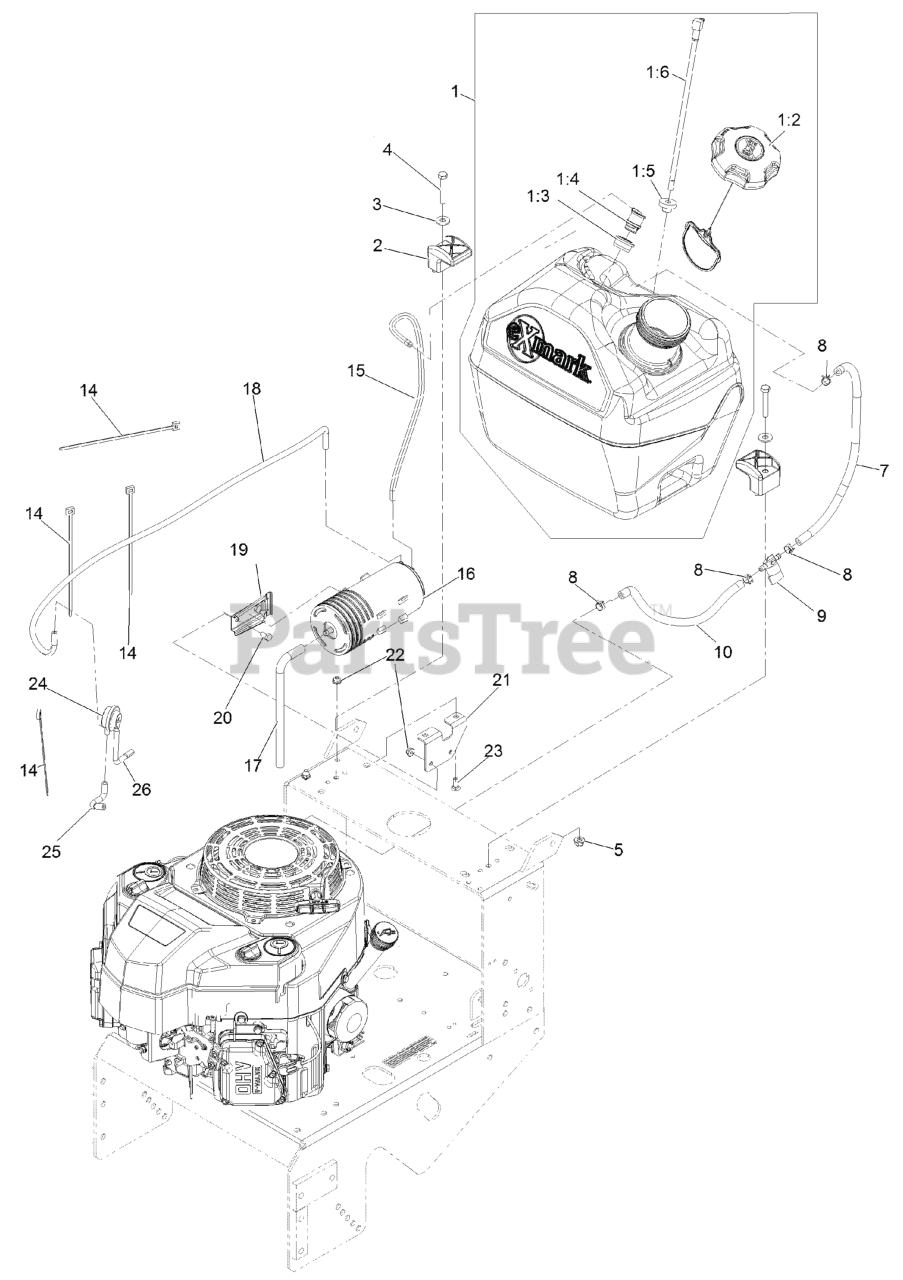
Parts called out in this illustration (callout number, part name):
1	ASM, FUEL TANK 5 GAL
1:2	CAP-FUEL, RATCHETING
1:3	GROMMET
1:4	VALVE-VENT, FUEL
1:5	BUSHING
1:6	FITTING, FUEL W/LINE AND SCREEN
3	WASHER-FLAT
4	SCREW-HH
5	NUT-HF, NI
7	HOSE-FUEL
8	CLAMP-HOSE
9	VALVE-FUEL
10	HOSE-FUEL
14	TIE-PLASTIC
15	HOSE-VENT
16	CANISTER-CARBON, 800CC
17	HOSE-VENT, CANISTER
18	HOSE-VENT, FORMED
19	BRACKET-CANISTER, CARBON
20	SCREW-HH
21	BRACKET-CANISTER, CARBON
23	BOLT-CARR
24	VALVE-CONTROL, VACUUM
25	HOSE-VENT, FORMED
26	HOSE-VENT, FORMED
